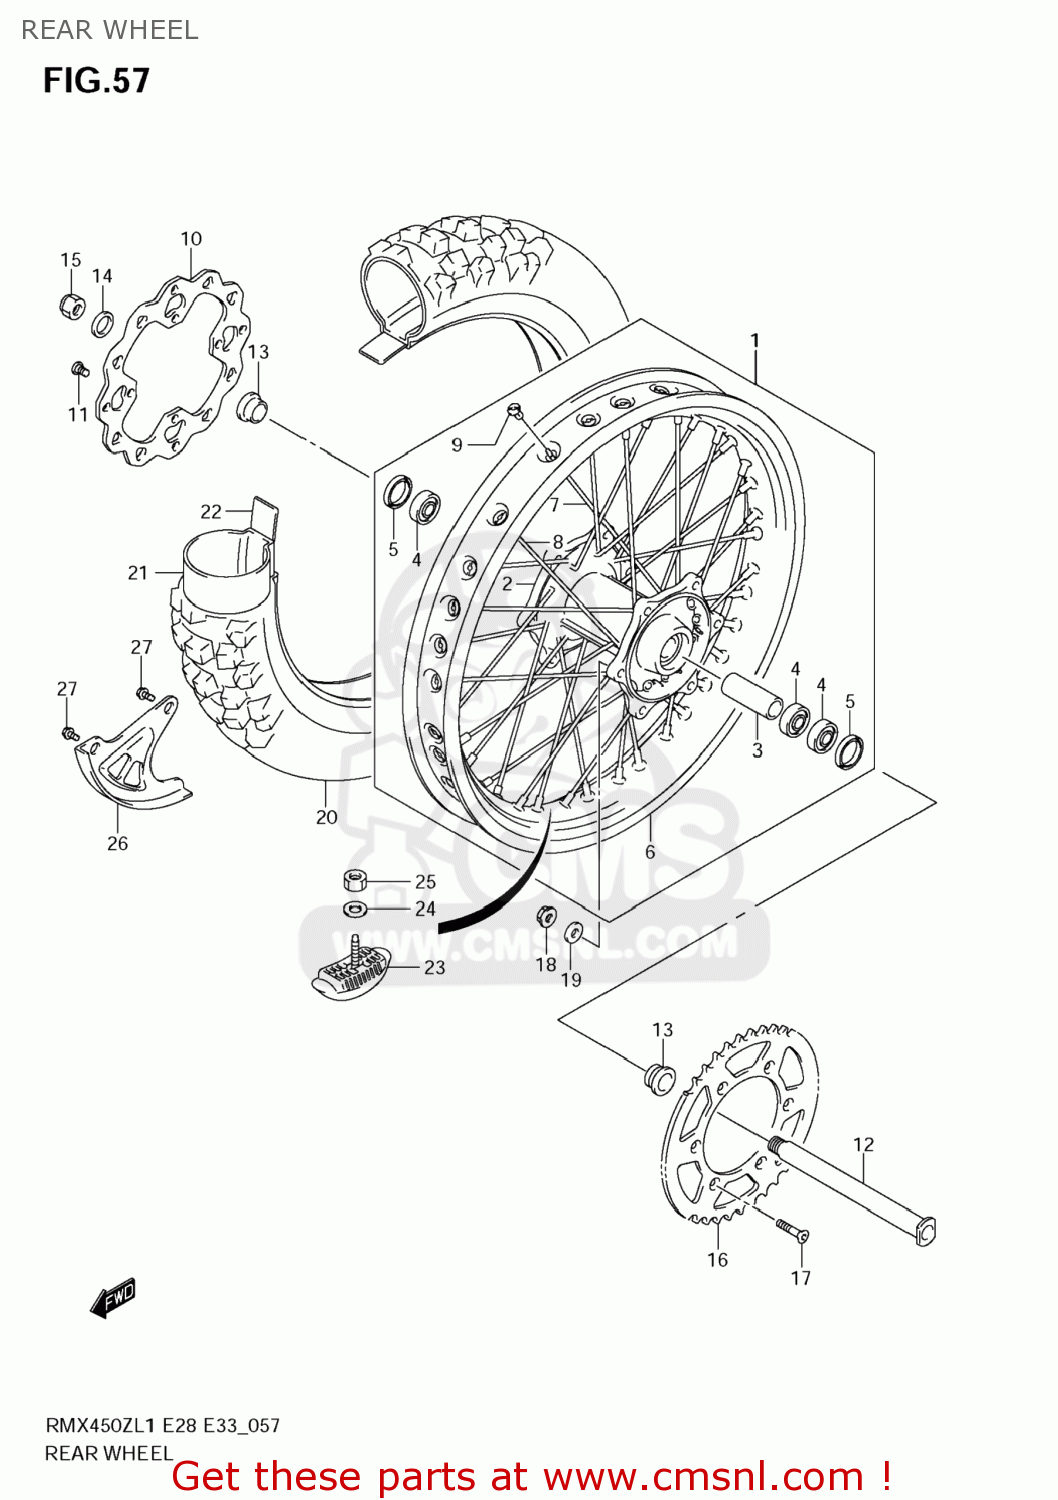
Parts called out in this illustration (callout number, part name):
1	WHEEL ASSY,RR
2	HUB,RR
3	SPACER,RR HUB BEARING
4	BEARING(25X42X9)
5	SEAL,OIL(32X43X7)
6	RIM,RR WHEEL(18X2.15 AL)(WHT)
7	SPOKE,RR WHEEL INNER
8	SPOKE,RR WHEEL OUTER
9	NIPPLE,RR WHEEL
10	DISC,RR BRAKE
11	SCREW(8X15)
12	AXLE,RR
13	SPACER,RR AXLE
14	WASHER(22X35X2)
15	NUT
16	SPROCKET,RR(51-520)
17	BOLT(8X28)
18	NUT
19	WASHER(8.5X16X1.2)
20	TIRE,RR(110/100 18 64M)
21	TUBE ASSY,WHEEL INNER
22	PROTECTOR,WHL INR TUBE
23	STOPPER,BEAD(2.15)
24	WASHER
25	NUT
26	COVER,RR DISC
27	BOLT(6X12)
